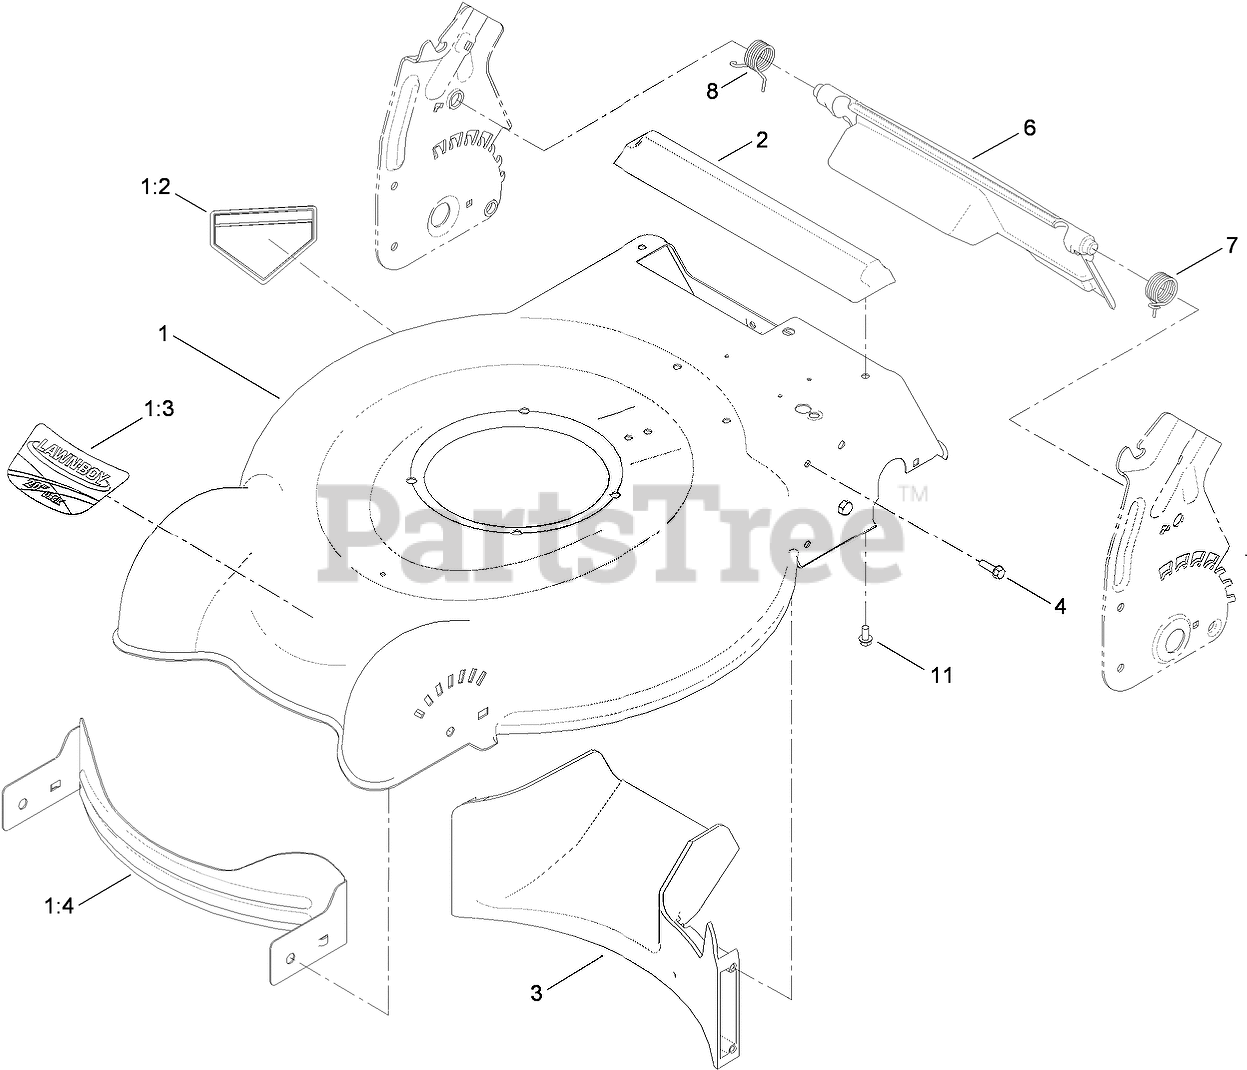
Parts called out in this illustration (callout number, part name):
1	HOUSING ASM
1:2	DECAL-DANGER
1:3	DECAL-DECK
1:4	BAFFLE-FRONT
2	CHUTE-REAR
3	BAFFLE-REAR
4	SCREW-HWH
6	REAR DEFLECTOR ASM
7	SPRING-TORSION, LH
8	SPRING-TORSION, RH
11	SCREW-PLASTITE
